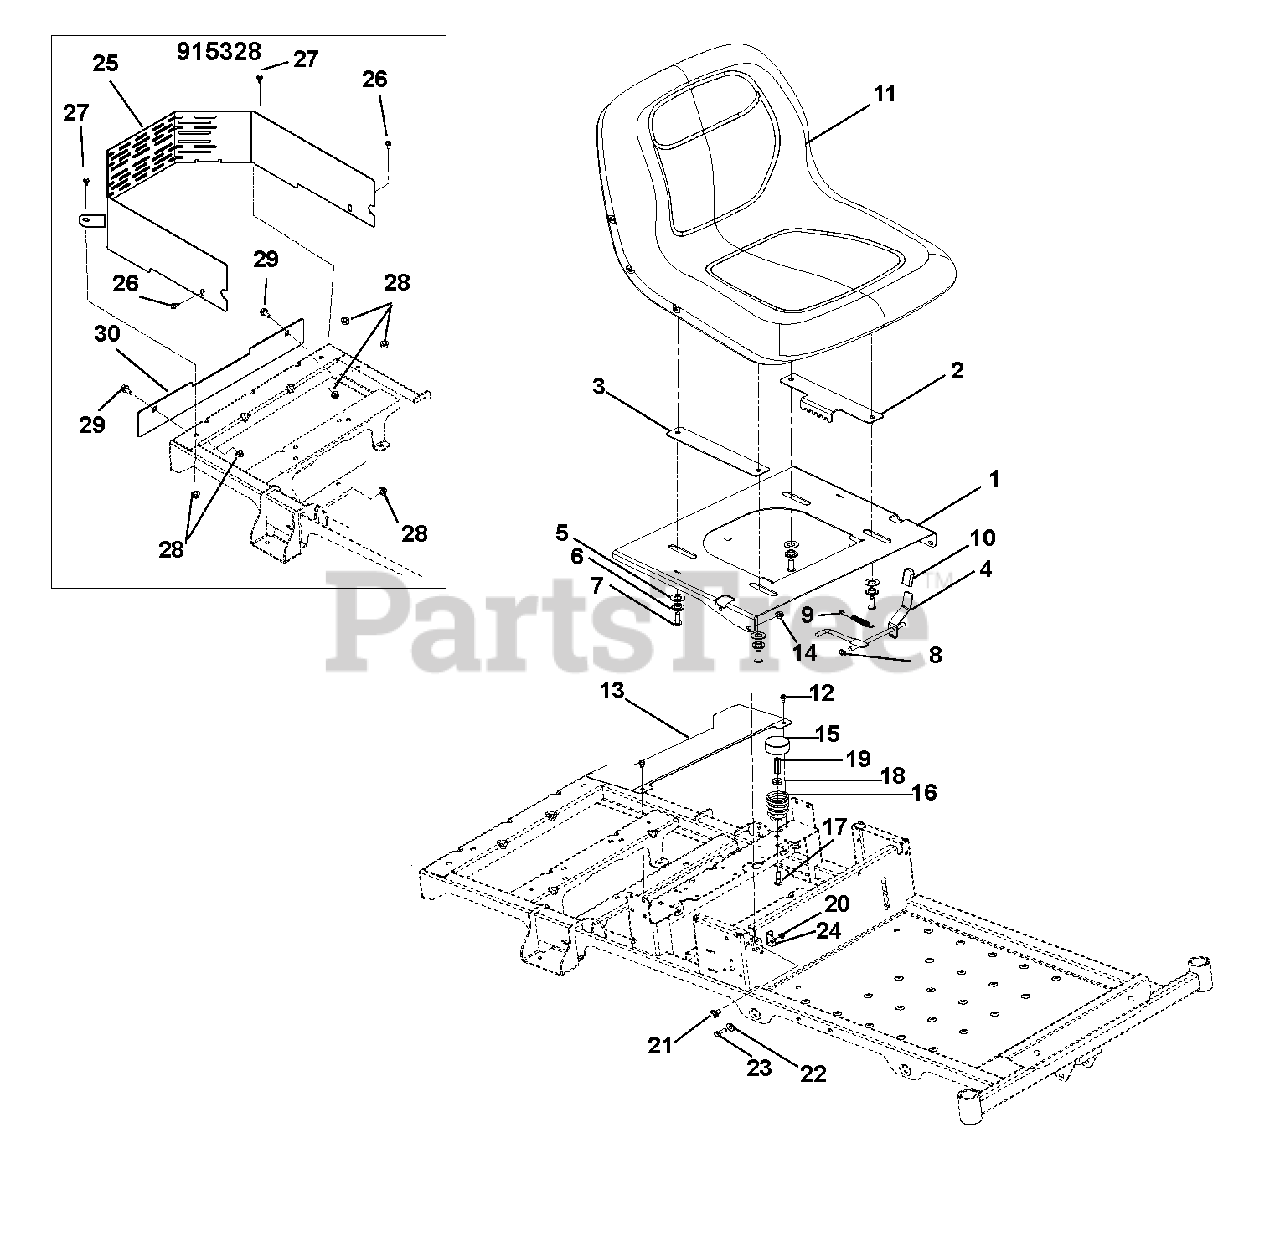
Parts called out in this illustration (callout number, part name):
1	Plate, Adjustable Seat
2	Plate, Adjustable Seat Track
3	Plate Adjustable Seat Slide
4	Weldment, Adjustable Seat Latch
5	Washer, Flat Steel .505 x 1.00 x .062
6	Bushing, Flange .32 x .500 x .344 x .880
7	Screw, Socket Head, Button Head .31-18 x 1.00
8	Push Nut 5/16
9	Weldment, Spring Tension .043 x .44 x 3.31, 5.8
10	Grip, Seat Lever, Grey
11	Seat, Milsco XB180 Grey
12	Screw, Tapping .25-20 x .50 Hex Washer Head Thread
13	Cover, Zoom CE Fan
14	Nut, .38-16 Locking Top Flange
16	Spring, Seat
17	Bolt, Round Head Square Neck .31-18 x 1.50
18	Washer, Flat Steel .328 x .87 x .179
19	Nut, Coupling 5/16-18 x 1.75
20	Nut, 5/16-18 Flange Nyloc
21	Bolt, Shoulder .375-16 x .135
22	Bushing, Flange .325 x .499 x .26 x .88
23	Bolt, Hex .31-18 x 1.00
24	Bracket, Seat Stop
25	Wall, Reach-In Zoom CE
26	Bolt, Hex .38-16 x .75 Grade 5 YWCZ
27	Bolt, Hex .38-16 x 1.00 Grade 5 YWZC
28	Nut, Locking Center .38-16
29	Bolt, Round Head Square Neck .38-16 x .75 Grade 5 YWZC
30	Flange, Muffler Zoom CE
